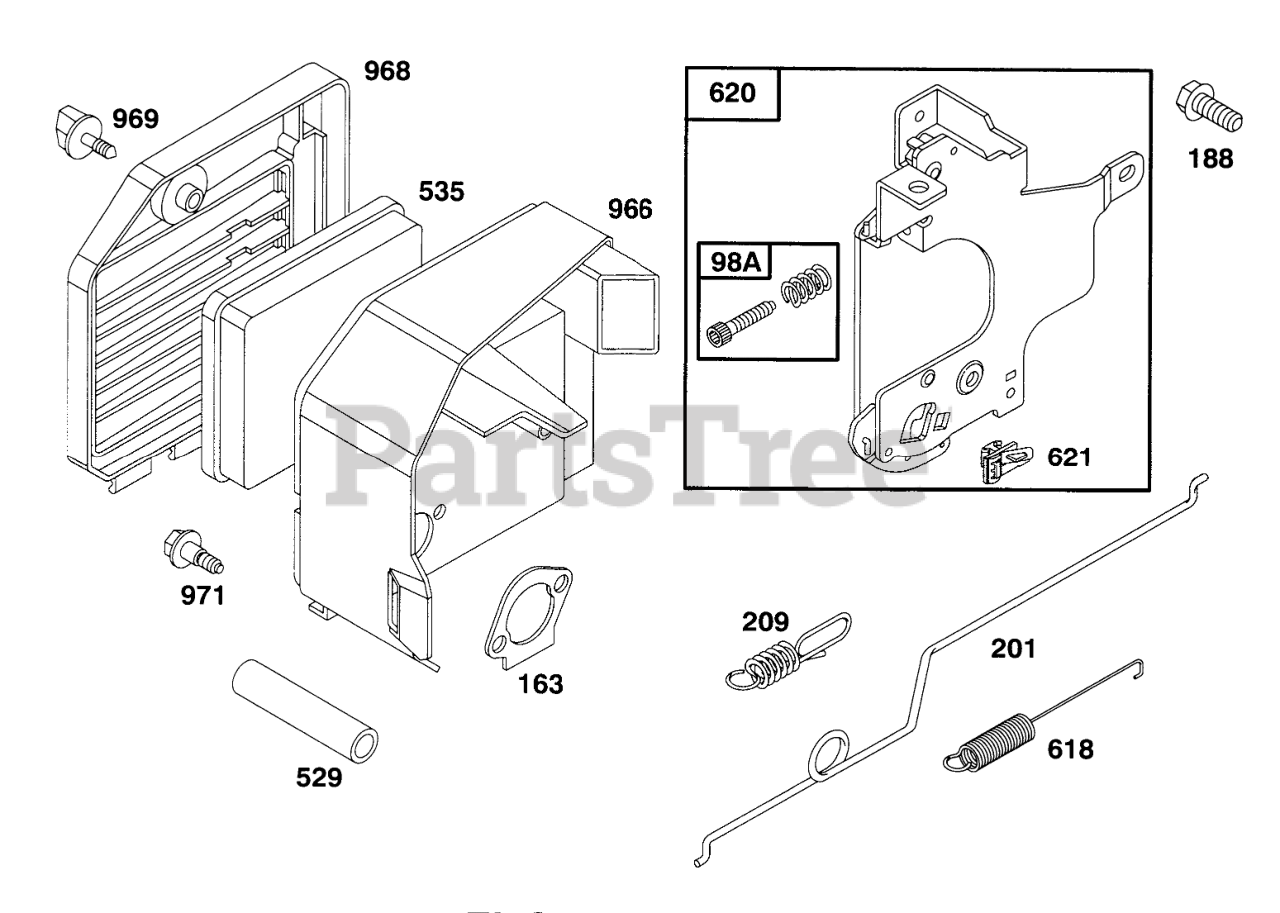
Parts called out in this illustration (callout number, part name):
98A	SPEED ADJUST. SCREW ASM
163	AIR CLEANER GASKET
188	Screw-Cap
201	GOVERNOR LINK
209	GOVERNOR SPRING
529	TUBE - BREATHER
535	FILTER ELEMENT
618	RETURN SPRING
620	CARBURETOR BRACKET
621	STOP SWITCH
966	AIR CLEANER BASE
968	AIR CLEANER COVER
969	AIR CLEANER SCREW
971	AIR CLEANER SCREW
